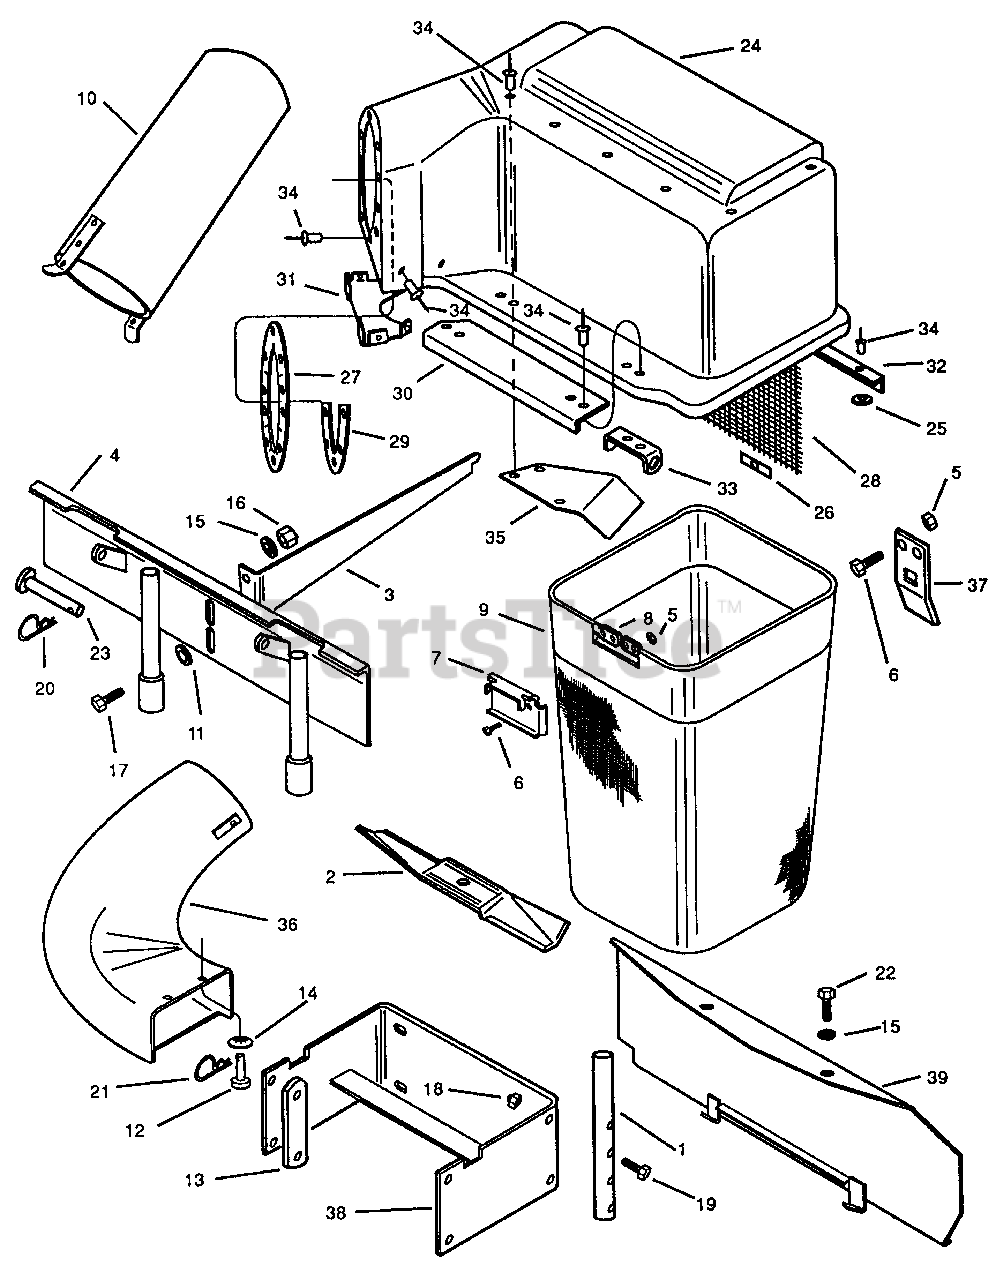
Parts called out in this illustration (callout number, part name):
1	Bar-Mounting
2	Blade-Mower
3	Bar-Cover Latch
4	Frame Assembly
5	Nut-Hex
6	Screw
7	Hanger-Bag
8	Frame-Bag
9	Grass Bag Assembly
10	Tube Assembly
11	Washer, Flat
12	Pin-Clevis
13	Spacer
14	Push Nut
15	Washer, Lock
16	Nut, Hex
17	Screw, Hex
18	Nut, Lock
19	Screw, Hex
20	Spring Clip
21	Spring Clip
22	Screw, Hex
23	Pin, Pivot
24	Cover & Decal Assembly
25	Washer
26	Strap-Screen Mounting
27	Gasket-Tube
28	Screen-Cover
29	Retainer-Gasket
30	Plate-Hinge
31	Plate-Comer
32	Angle-Cover
33	Hinge
34	Rivet
35	Deflector
36	Chute & Decal Assembly
37	Latch-Cover
38	Bracket & Decal Assembly
39	Baffle Assembly
